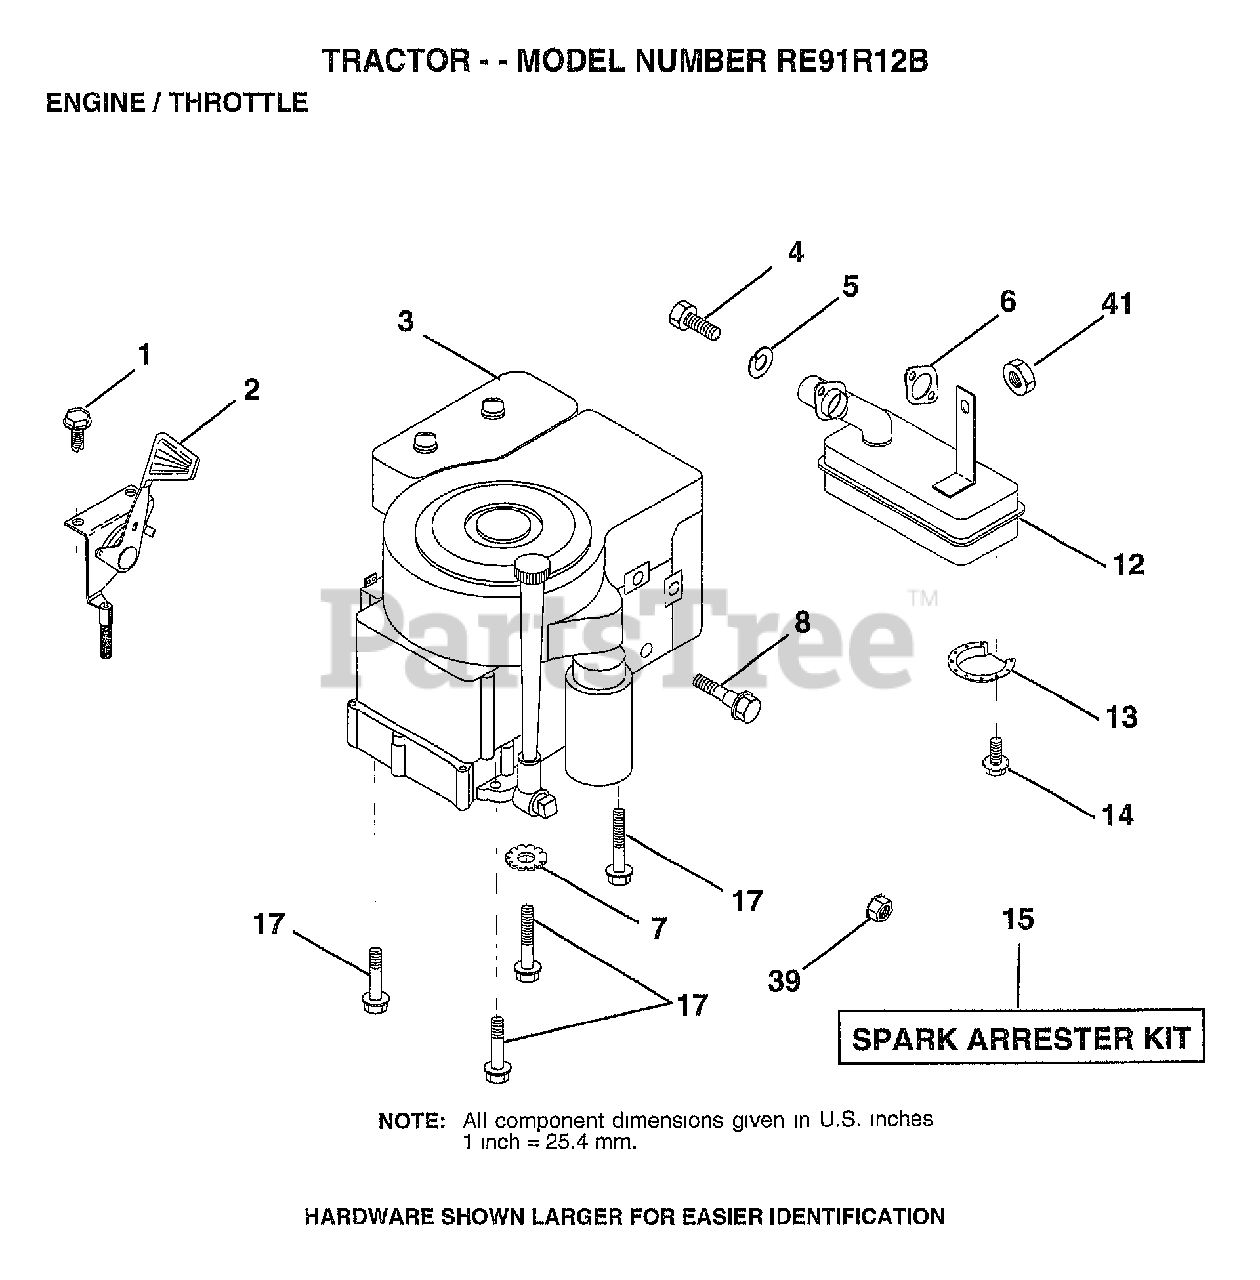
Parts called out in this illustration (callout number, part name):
1	SCREW.1/4-20X1/2
2	"CONTROL,THROTTLE"
4	SCREW HEX HD CAP
5	LOCKWASHER
6	GASKET ENG 1 313 LD TIN PLATED
7	LOCKWASHER
8	SHOULDER BOLT ST
12	MUFFLER-TECH 13HP
13	DEFLECTOR.222573
17	SCREW LT
39	NUT
41	"NUT HEX,LOCK,FLAN"
